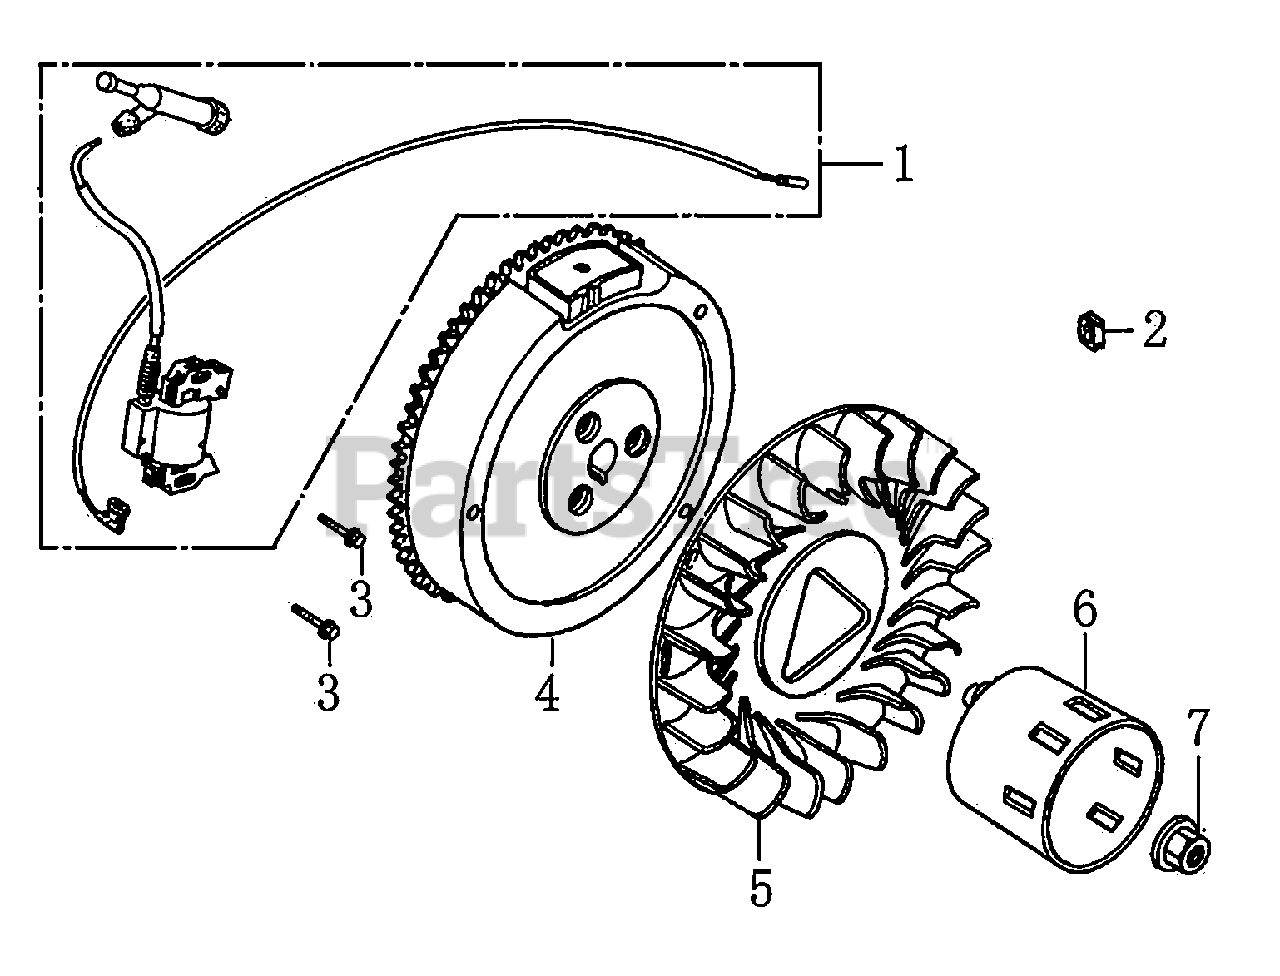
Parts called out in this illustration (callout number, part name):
1	COIL ASSY., IGNITION
2	GROMMET, CORD
3	BOLT, FLANGE, M6X25
4	FLYWHEEL COMP
5	FAN COOLING
6	PULLEY, STARTER
7	NUT SPECIAL, 16MM
